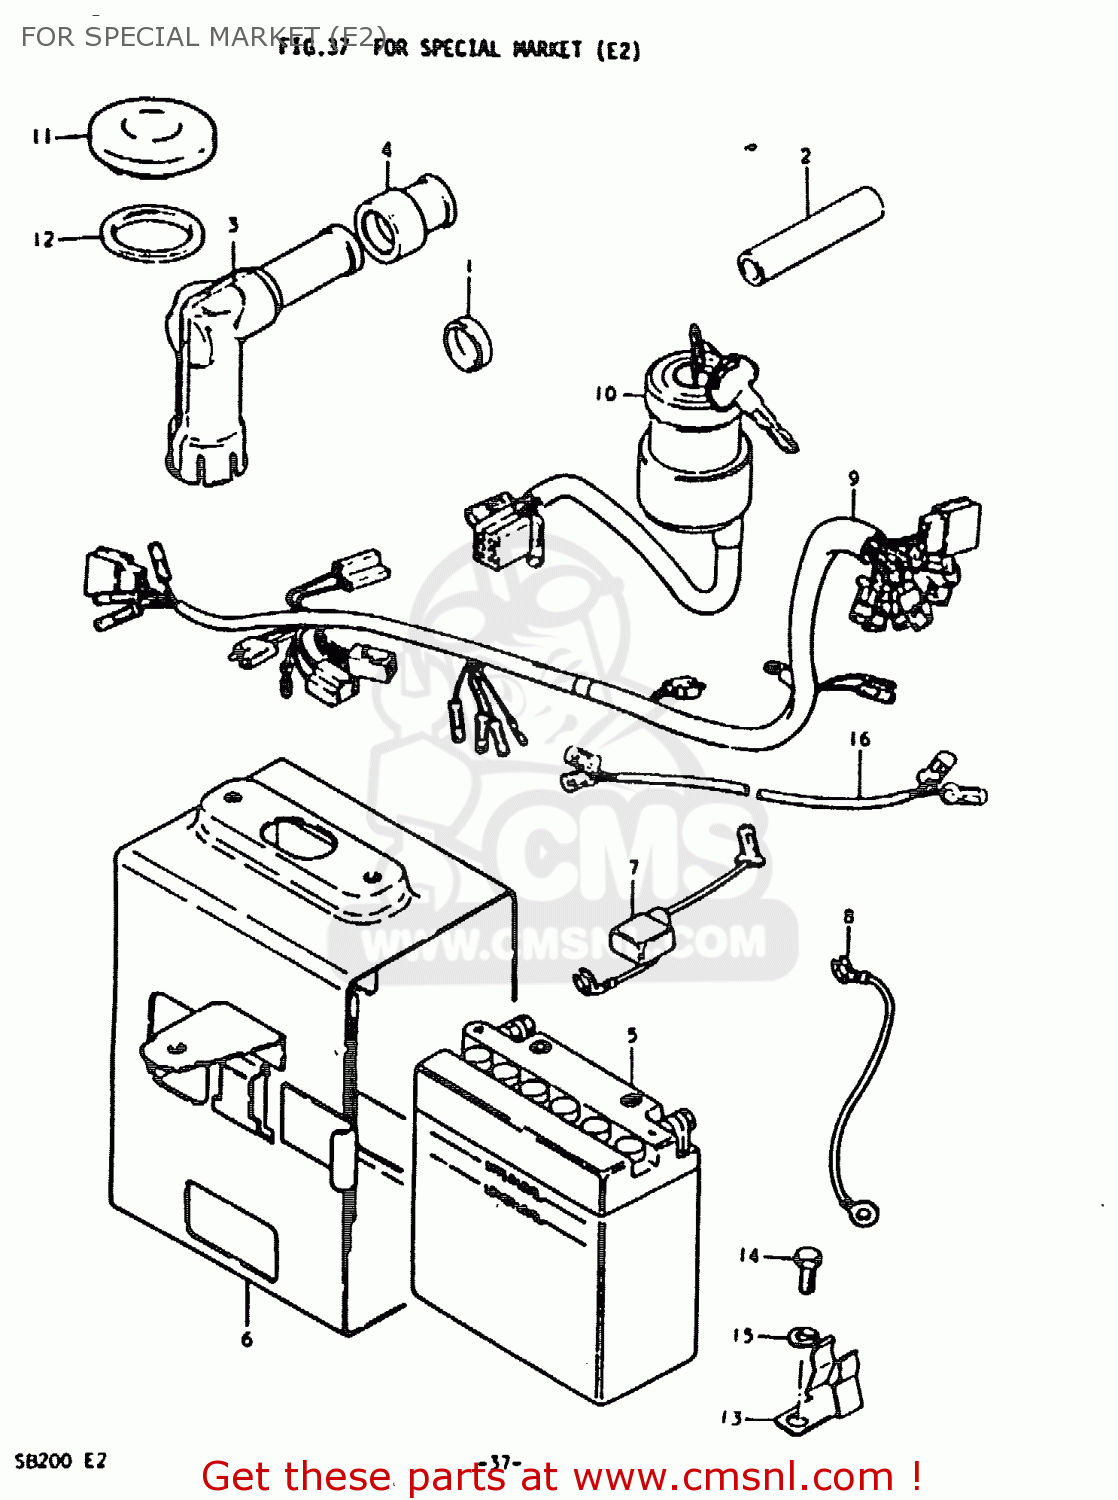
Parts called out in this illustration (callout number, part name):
1	PLUG
2	PIN(7.4X13X56)
3	CAP,SPARK PLUG
4	SEAL,SPARK PLU
5	BATTERY ASSEMBLY (12V)
6	HOLDER, BATTERY
7	LEAD WIRE, BATTERY (+)
8	LEAD WIRE, BATTERY (-)
9	WIRING HARNESS
10	SWITCH ASSY, IGNITION
11	CAP,FUEL TANK
12	GASKET (NAS)
13	HOLDER,FUSE CASE
14	BOLT
15	LOCK WASHER
16	LEAD WIRE, HORN
